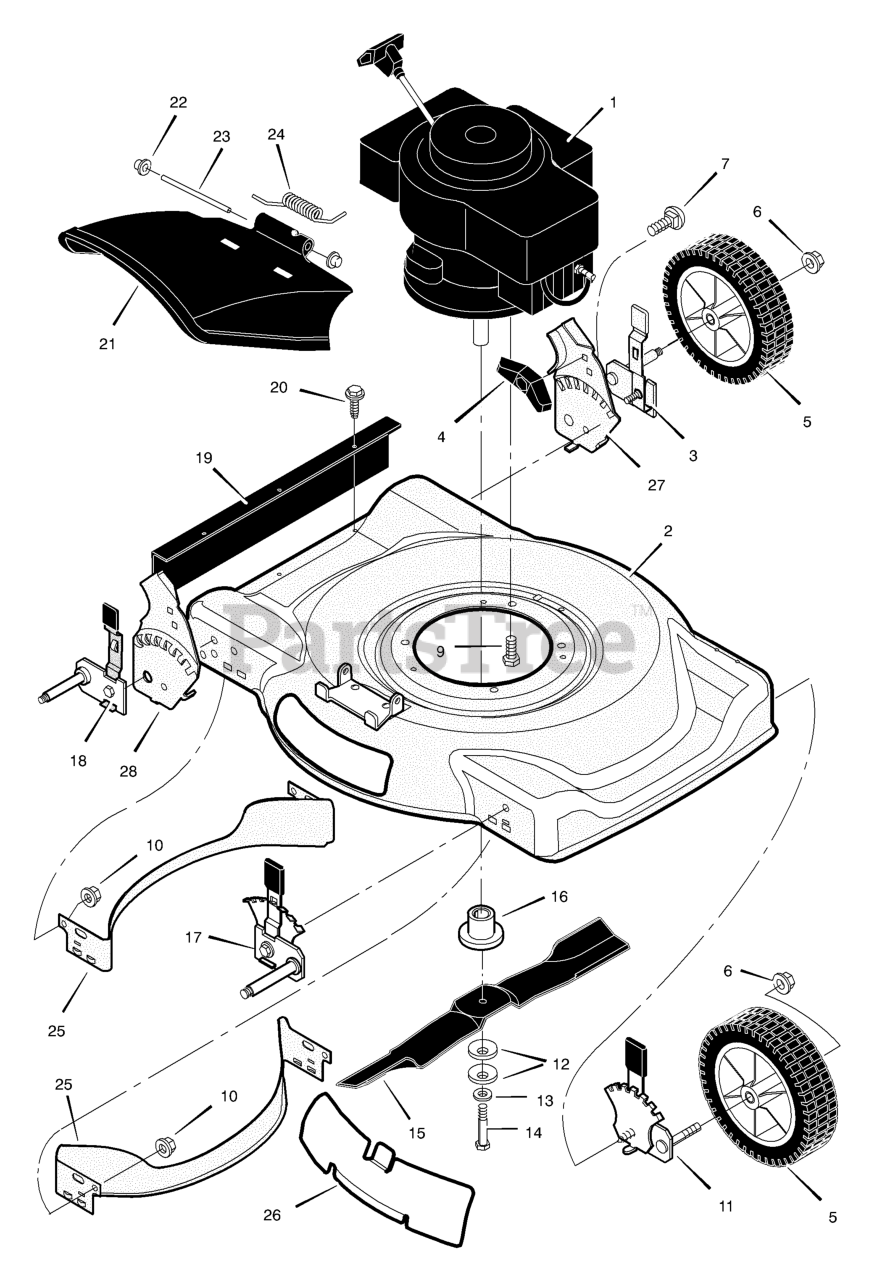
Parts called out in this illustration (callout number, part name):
1	Engine, Briggs & Stratton *
2	Housing
3	Height Adjuster, Left Rear
5	Wheel and Tire
6	Locknut, Flange
7	Bolt, Carriage
9	Bolt, Engine
10	Nut
11	Height Adjuster, Left Front
12	Washer, Belleville
14	Bolt, Hex
16	Adapter, Blade
17	Height Adjuster, Right Front
18	Height Adjuster, Right Rear
19	Guard, Rear
21	Deflector, Chute
22	Push-On Cap
23	Pin, Pivot
25	Baffle
26	Plate, Mulcher
27	Bracket, Left Handle
28	Bracket, Right Handle
